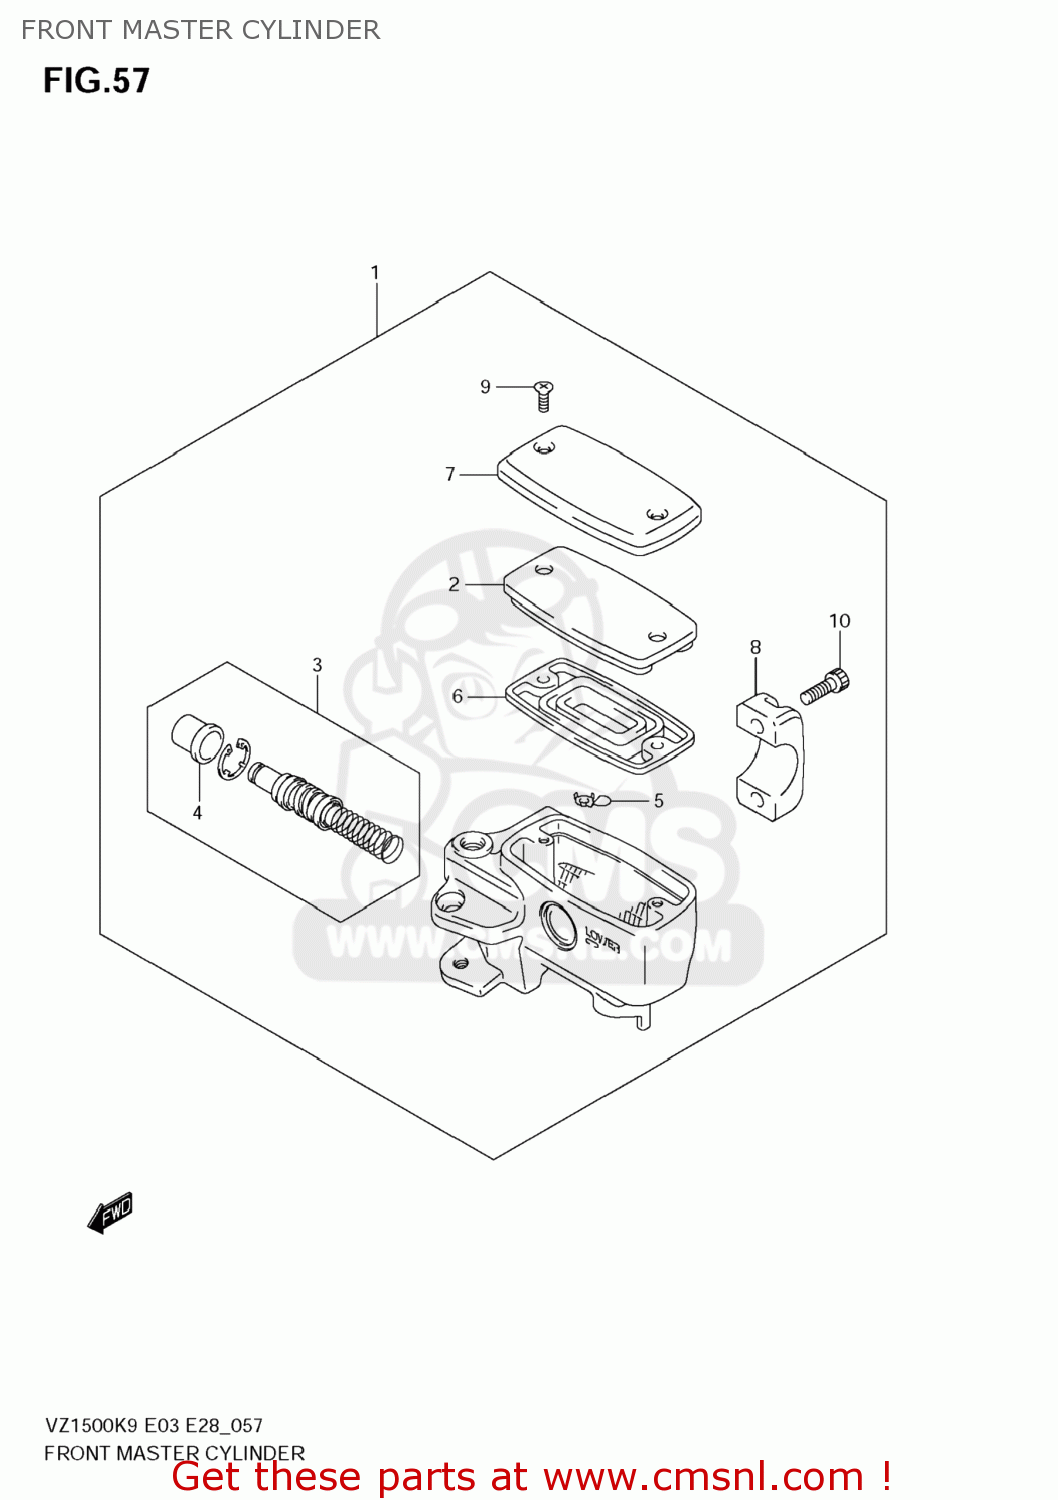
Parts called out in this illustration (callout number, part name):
1	CYLINDER ASSY,FR MASTER
2	PLATE,DIAPHRAGM
3	PISTON/CUP SET
4	BOOT
5	PROTECTOR
6	DIAPHRAGM
7	CAP
8	HOLDER
9	SCREW
10	BOLT
